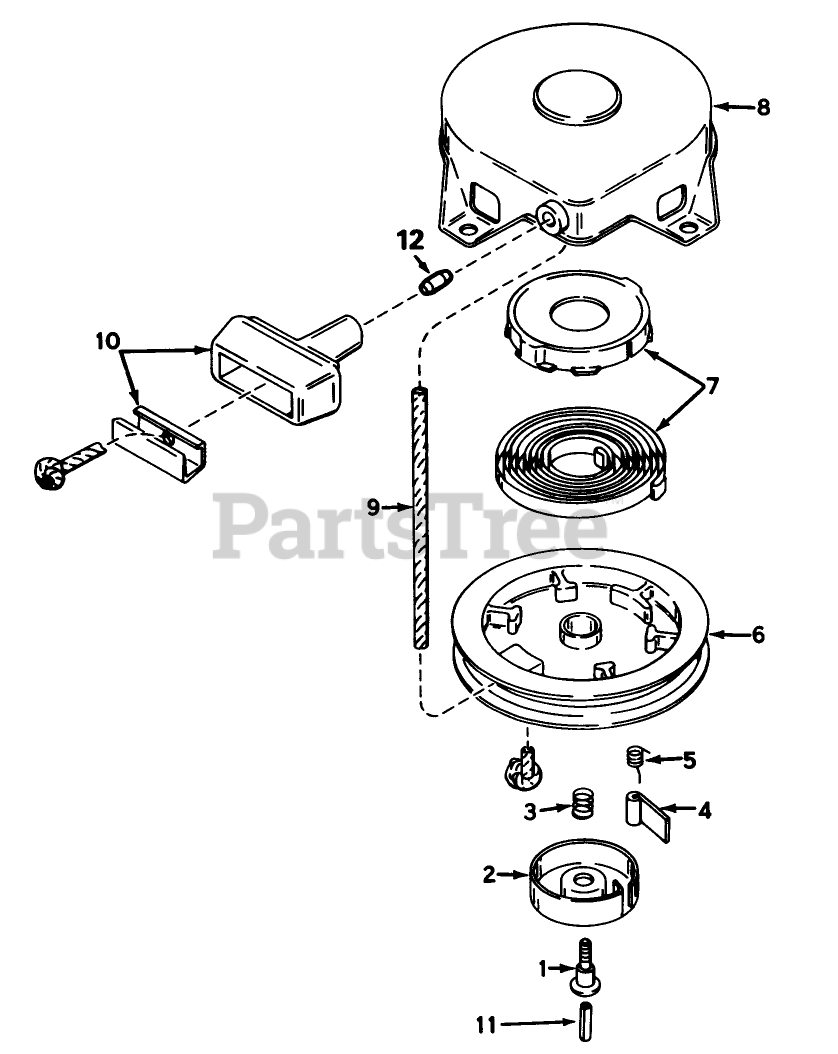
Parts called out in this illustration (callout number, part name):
2	Retainer
3	Spring-Brake
4	Dog-Starter
5	Spring-Dog
7	Spring & Keeper Assy
8	Housing Assy.-Starter (Incl. #1)
9	Rope-Starter (98 cut to length)
10	Assy., Starter
11	Centering
12	Retainer-Starter Rope
